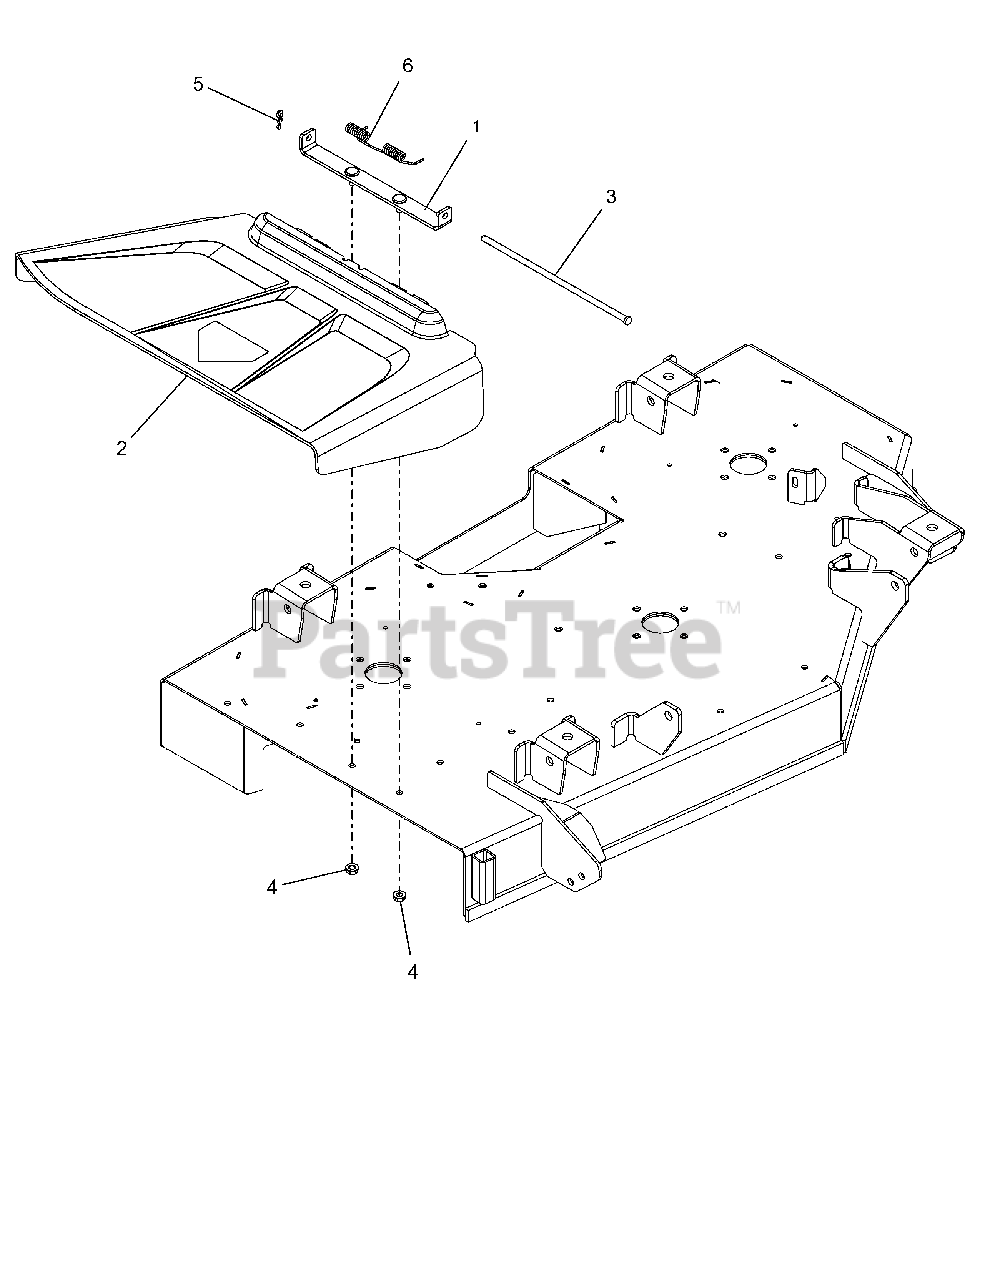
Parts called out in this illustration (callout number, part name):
1	WLDMT, CHUTE MT BRKT
2	CHUTE, SIDE DISCHARGE
3	PIN, 5/16 X 10.5
4	@NUT-LK-TOP-FLG .31-18 YWZC
5	PIN-HAIR INT .08X.18X1.18 YWZC
6	SPRING-TORSION
